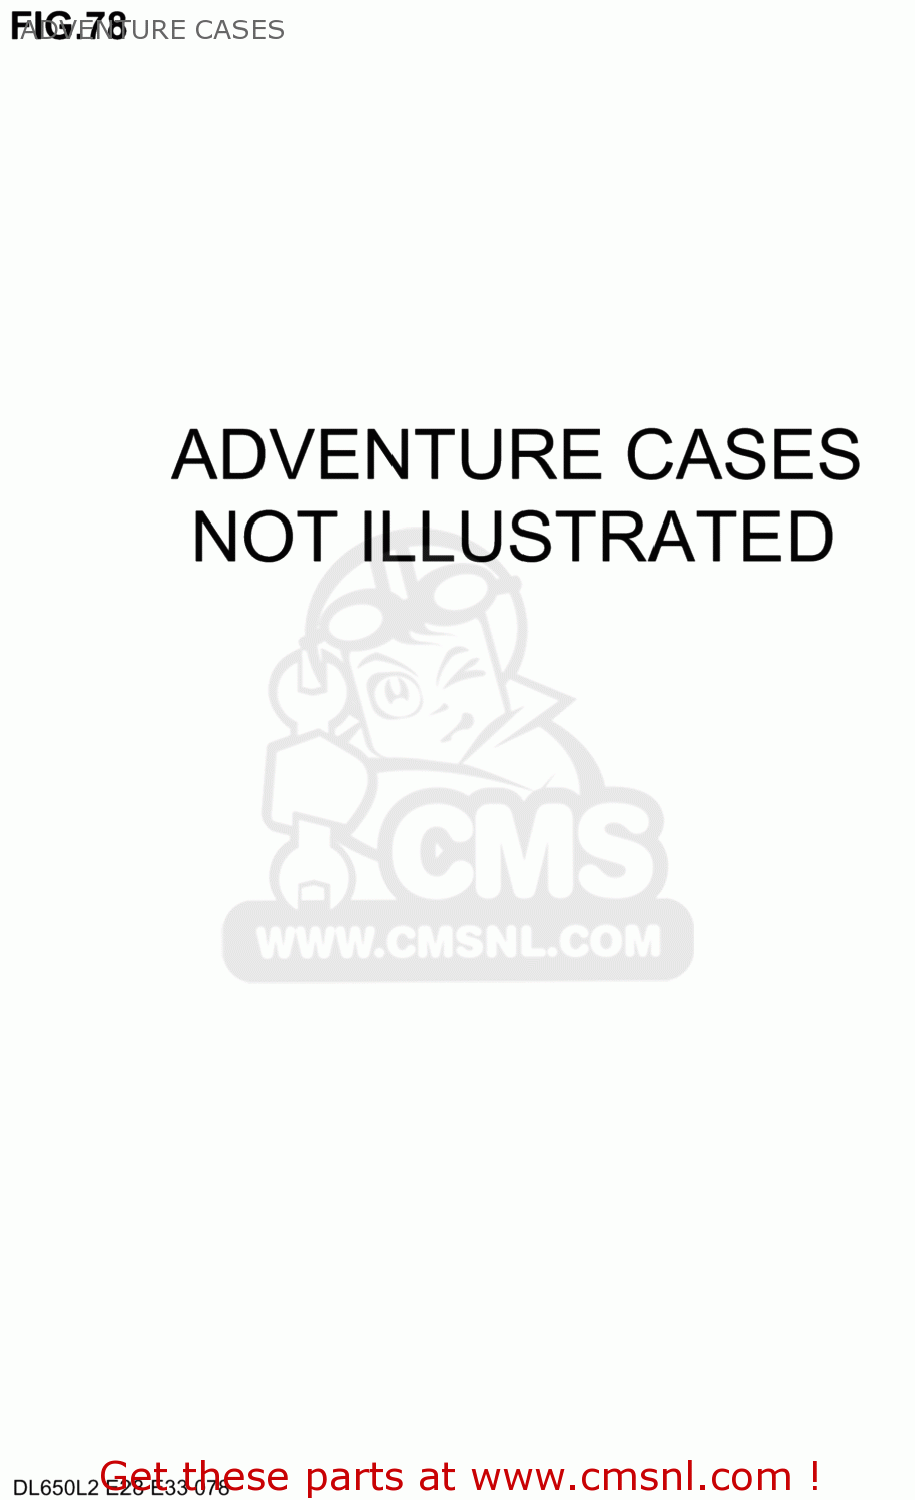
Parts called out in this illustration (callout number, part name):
1	ACCESSORY BAR
2	DL6 ACCY BAR, L
3	DL6 ACCY BAR, R
4	DL6 ADV ACCY BA
5	Side Case Carrier Set
6	DL650L2 LH SC M
7	DL650L2 RH SC M
8	DL650L2 SC MNT
9	DL650L2 SC/MT C
10	Side Case Installation Kit
11	TC CARRIER
12	DL6L2 T/C MTG H
13	Aluminum Side Case Set, Black
14	DL650AL2 ALM LH
15	DL650AL2 ALM RH
16	DL650 ADV S/C R
17	Vario Touring Windshield
18	DL650 WINDSCREE
19	6-Piece Lock Set
